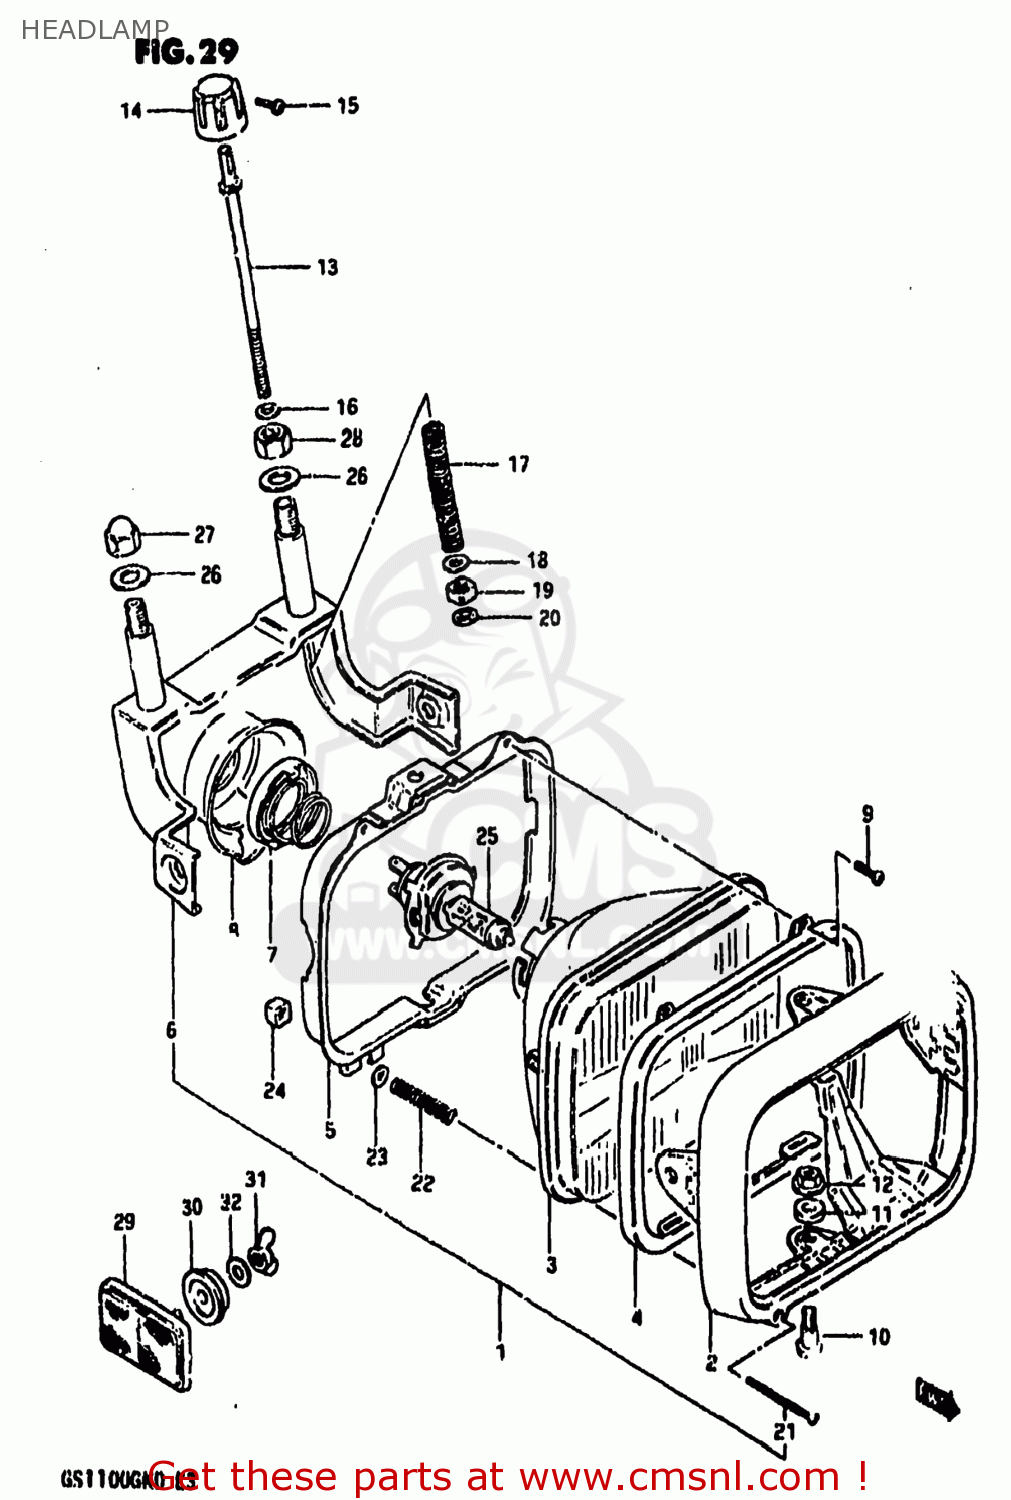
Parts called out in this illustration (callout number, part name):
1	HEADLAMP ASSEMBLY
2	RIM,HEADLAMP
3	LAMP UNIT
4	RETAINER,HEADLAMP
5	RING,MOUNTING
6	HOUSING
7	HOLDER
8	COVER,HEADLAMP SOCKET
9	SCREW
10	SCREW
11	SPACER
12	NUT,ADJUSTING
13	SCREW,HEADLAMP ADJUST
14	KNOB,ADJUSTER
15	SCREW 3X12
16	WASHER
17	SPRING,HEADLAMP ADJUST
18	WASHER
19	SPACER
20	NUT,HEADLAMP ADJUSTER
21	SCREW,HEADLAMP ADJUST
22	SPRING,HEADLAMP ADJUST
23	WASHER
24	NUT
25	BULB(12V60/55W,H4)
26	WASHER
27	NUT
28	NUT
29	REFLECTOR,REFLEX
30	SPACER,FRONT REFLEX REFLECTOR
31	NUT, WING
32	WASHER
